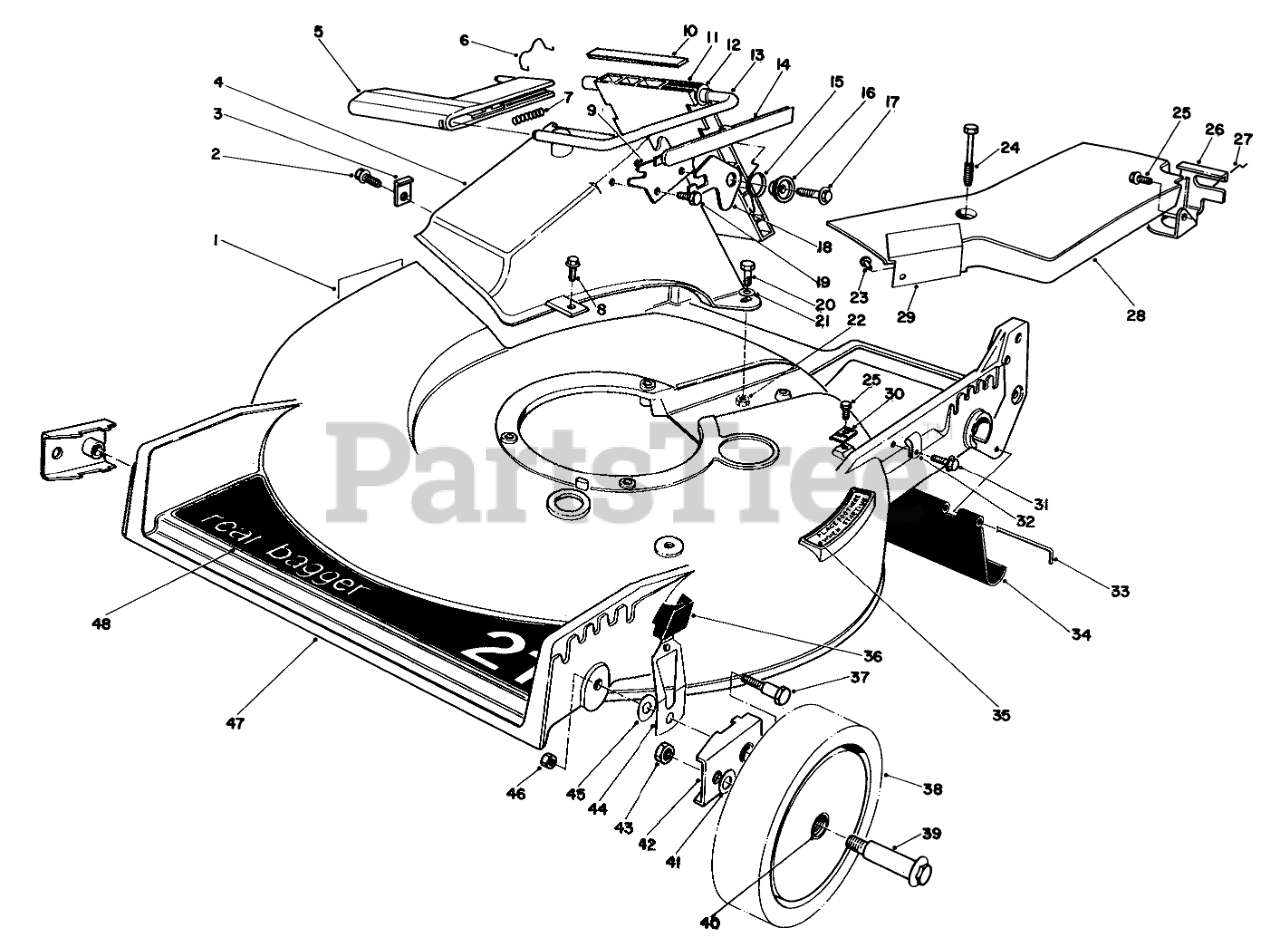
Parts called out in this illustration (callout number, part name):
1	DECAL-DANGER
2	SCREW
3	TUNNEL CLIP
4	Tunnel Discharge
5	Handle-Door
6	DOOR RET SPRING
7	Spring
8	Screw
9	DOOR LATCH PLATE
10	DOOR COVER
11	Door Discharge
12	BUSHING-NYLON
13	DOOR ROD +
14	DOOR HANDLE COVER
15	TORSION SPRING
16	DOOR SPACER
17	SCREW-HWH
18	SAFETY LATCH
19	SCREW-PLASTITE
20	SCREW-HH
21	WASHER-FLAT
22	NUT-LOCK, NI
23	RIVET-HEAD, FLAT
24	SCREW-HHFTF
25	SCREW-HWHTF
26	Bracket-Traction Adj.
27	RETAINER-CABLE
28	Belt Cover Assembly (Incl.Ref. #23 & 29)
29	HEAT SHIELD
30	Cable Clamp
31	SCREW
32	CLAMP-CABLE
33	ROD-SHIELD
34	SHIELD-TRAILING
35	STEP PAD DECAL
36	KNOB-ARM
37	PIVOT SCREW
38	Wheel & Tire Assembly (Incl.Ref. #40)
39	BOLT-WHEEL
40	BUSHING
41	WASHER
42	HP PIVOT ARM ASM
43	Nut
44	Spring Arm
45	WASHER-PIVOT
46	NUT-LOCK, NI
47	Housing (Incl. Ref. #1 & 35)
48	DECK DECAL
